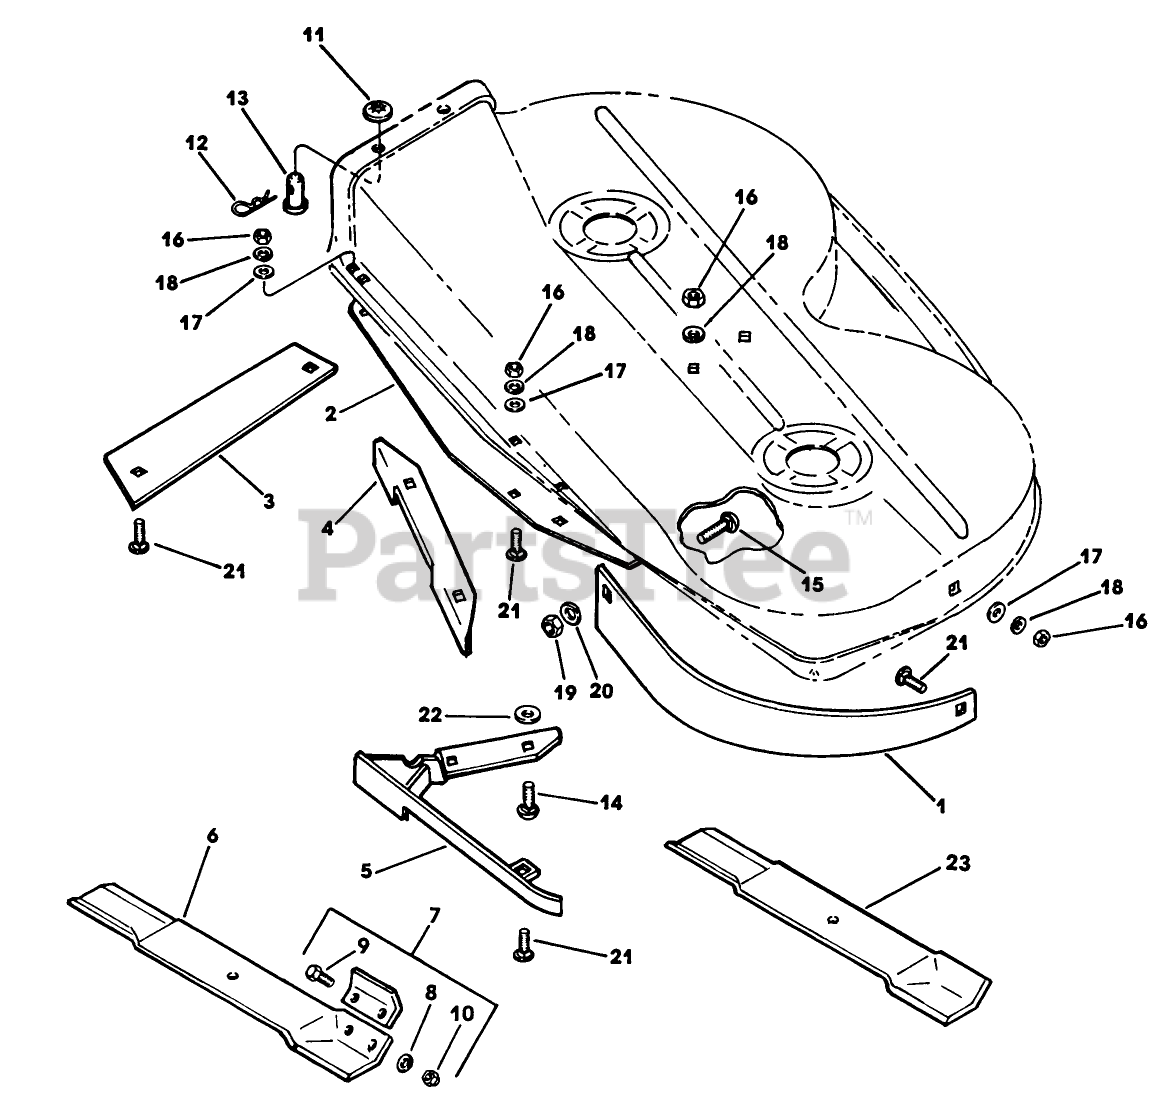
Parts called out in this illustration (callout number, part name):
3	BAFFLE
6	BLADE - MOWER
7	KIT-BLADE EXTENSION (38" LB)
9	SCREW - HEX
10	Nut, Hex Cone Lock
12	PIN - SPRING CLIP
13	PIN-CLEVIS
16	NUT SS
19	NUT
20	WASHER
23	BLADE - MOWER
